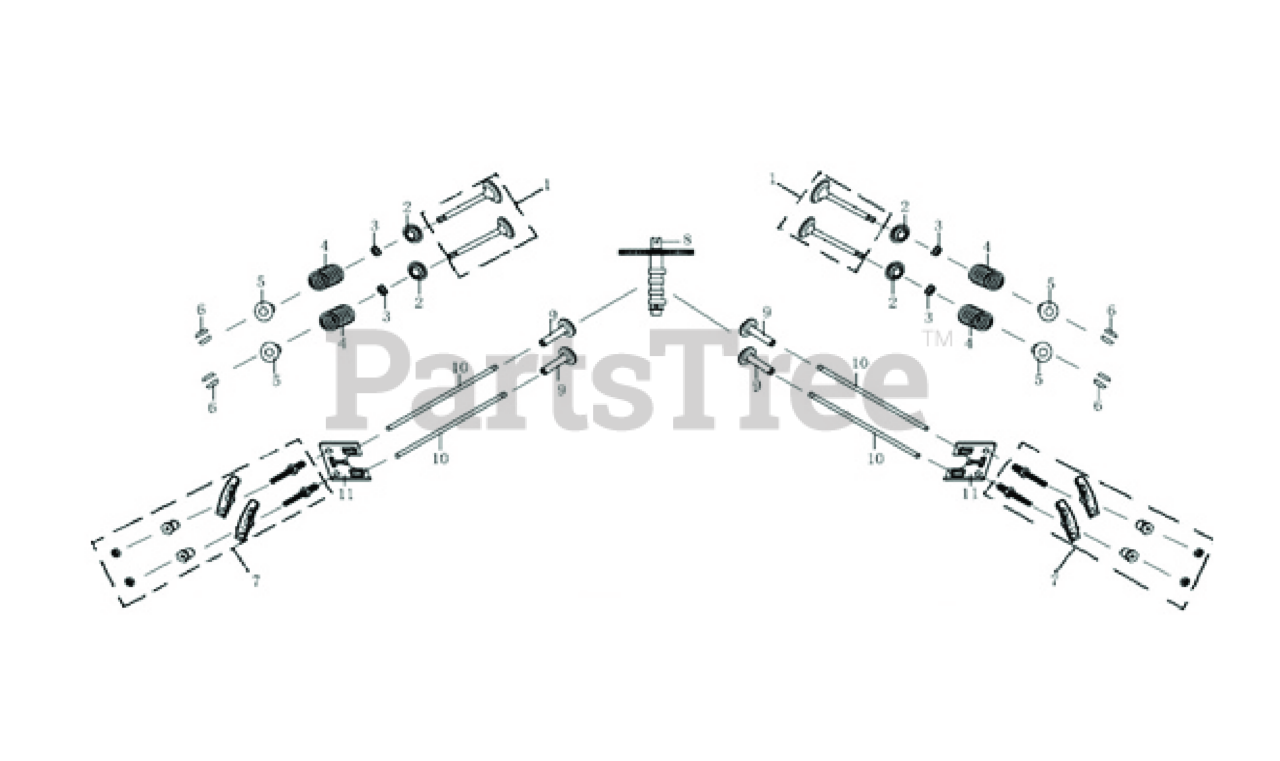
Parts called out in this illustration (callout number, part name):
1	Valve Set, Intake & Exhaust
2	Bushing, .752 Oilite
3	Oil Seal, Valve
4	Spring, Inner Valve
5	Retainer, Valve Spring
6	Valve Keeper
7	Rocker Arm Assembly
8	Camshaft
9	BUSHING, BRONZE - .376 ID X .627 OD
10	Push Rod
11	Guide, Push Rod
